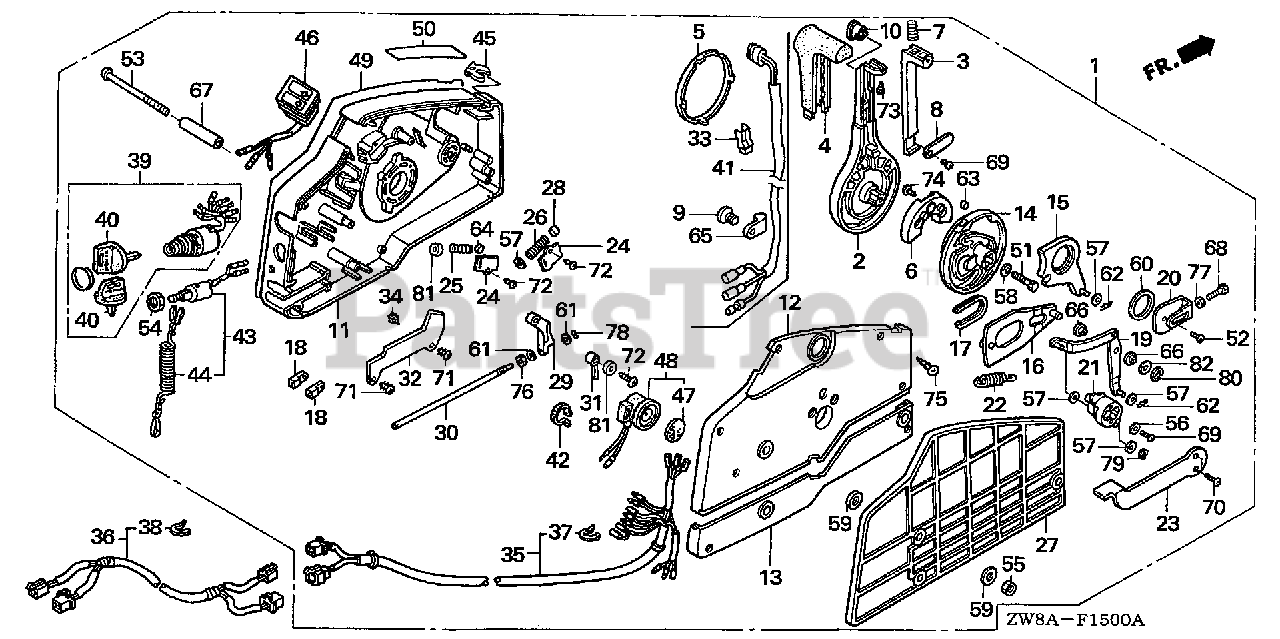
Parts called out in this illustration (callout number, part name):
1	BOX ASSY., REMOTE CONTROL
2	HANDLE, REMOTE CONTROL
3	LEVER, HANDLE LOCK
4	GRIP, REMOTE CONTROL HANDLE
5	CAP, HANDLE
6	BLOCK, NEUTRAL LOCK
7	SPRING, REMOTE CONTROL HANDLE
8	PLATE, LEVER SETTING
10	COVER, GRIP
11	HOUSING, REMOTE CONTROL BOX (A)
12	HOUSING, REMOTE CONTROL BOX (B)
13	HOUSING, REMOTE CONTROL BOX (C)
14	WHEEL, CONTROL
15	ARM, SHIFT LINK
16	PLATE, SLIDING
17	COLLAR, SLIDING PLATE
18	PIVOT, SHIFT
19	ARM, LINK JOINT
20	BRACKET, LINK JOINT
21	WHEEL, ACCELERATOR
22	SPRING, ACCELERATOR WHEEL
23	LEVER, IDLE
24	PLATE, SPRING SETTING
25	SPRING, SHIFT CLICK
26	SPRING, CHOKE RETURN
27	SPACER, REMOTE CONTROL BOX
28	SPACER, CLICK SPRING
29	BLOCK, THROTTLE FRICTION
30	BOLT, FRICTION
31	SPACER, NEUTRAL SWITCH
34	SPACER, CABLE CLAMP
35	CABLE ASSY. B, REMOTE CONTROL (4P+4P)
36	CABLE ASSY., REMOTE CONTROL EXTENSION (4P+4P)
37	TIE, CABLE (2.4X92) (NATURAL)
38	TIE, CABLE (2.4X92) (NATURAL)
39	SWITCH ASSY., COMBINATION
40	KEY ASSY., COMBINATION SWITCH (35100-ZV5-003 ONLY)
42	BAND (BLACK 3.5X140)
43	SWITCH ASSY., EMERGENCY STOP
44	WIRE, EMERGENCY
45	CLIP, EMERGENCY LOCK
46	LAMP ASSY., INDICATOR
47	PLATE, TURN SIGNAL BUZZER
48	BUZZER, WARNING
49	PLATE, REMOTE CONTROL (CAUTION PICT=SILVER)
50	MARK, FAST IDLE
51	BOLT, HEX. (8X35)
52	SCREW, PAN (6X10)
53	SCREW (6X95)
54	NUT, HEX. (16MM)
55	NUT, HEX. (6MM)
56	WASHER, PLAIN (5MM)
57	WASHER, PLAIN (6MM)
58	WASHER, PLAIN (8MM)
59	WASHER (6MM)
60	WASHER (28MM)
61	WASHER, PLAIN (4MM)
62	PIN, LOCK (6MM)
64	ROLLER, CLICK
66	COLLAR, LINK JOINT
67	COLLAR, DISTANCE (6X10X43.5)
68	BOLT, HEX. (5X16)
69	SCREW, PAN (5X10)
70	SCREW, OVAL (5X12)
72	SCREW, TAPPING (5X10)
73	SCREW, TAPPING (5X12)
74	SCREW, TAPPING (6X16)
75	SCREW, TAPPING (5X25)
76	NUT, HEX. (6MM)
77	NUT, HEX. (5MM)
78	E-RING (3MM)
79	E-RING (4MM)
80	E-RING (7MM)
81	WASHER, PLAIN (5MM)
82	WASHER, PLAIN (8MM)
